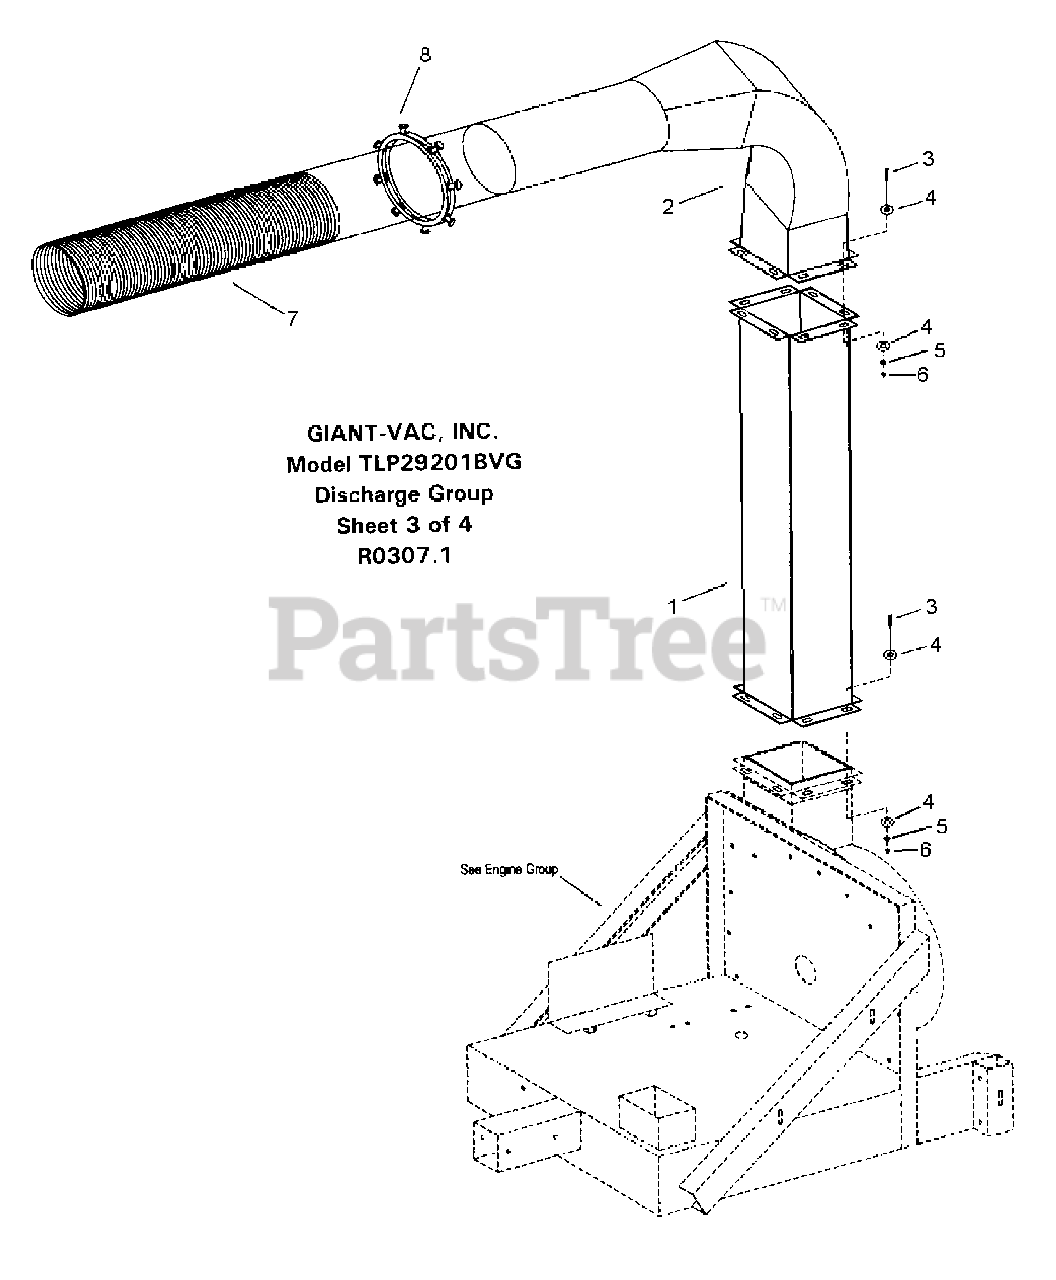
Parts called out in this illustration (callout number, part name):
1	Discharge Stack
2	Discharge Elbow
3	3/8-16 x 1-1/4" Hex Bolt
4	3/8 Flat Washer
5	3/8 Lock Washer
6	3/8-16 Hex Nut
7	Hose, Discharge 8" x 5' Metal
8	Ring, Squeeze 8"
